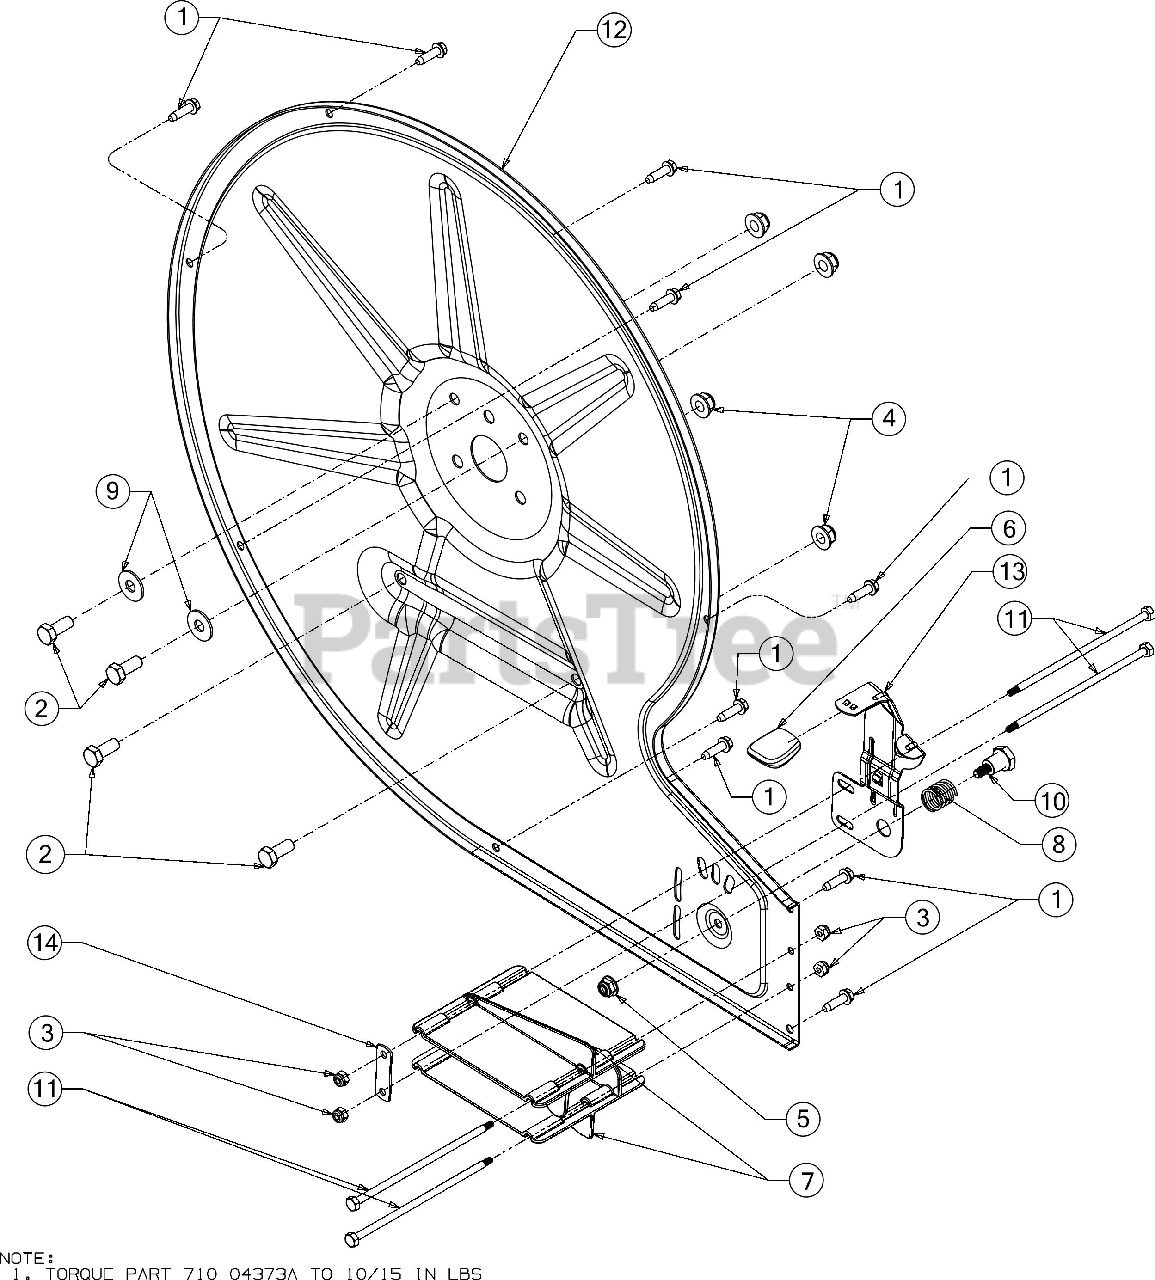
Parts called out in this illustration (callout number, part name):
1	SCREW #12-16 .75
2	SCREW 5/16-18 x .75 GR5
4	FLANGE LOCK NUT 5/16-18
5	FLANGE LOCK NUT
6	HEIGHT ADJUSTMENT KNOB
7	LOUVER BLOWER PLATE
8	COMPRESSION SPRING
9	BELL WASHER .337 X.867 x .057
10	SHOULDER SCREW .437X.50 1/4-20
11	SHOULDER SCREW 18 x 4.8 8-32 GR5
14	GUIDE LOUVER PLATE
